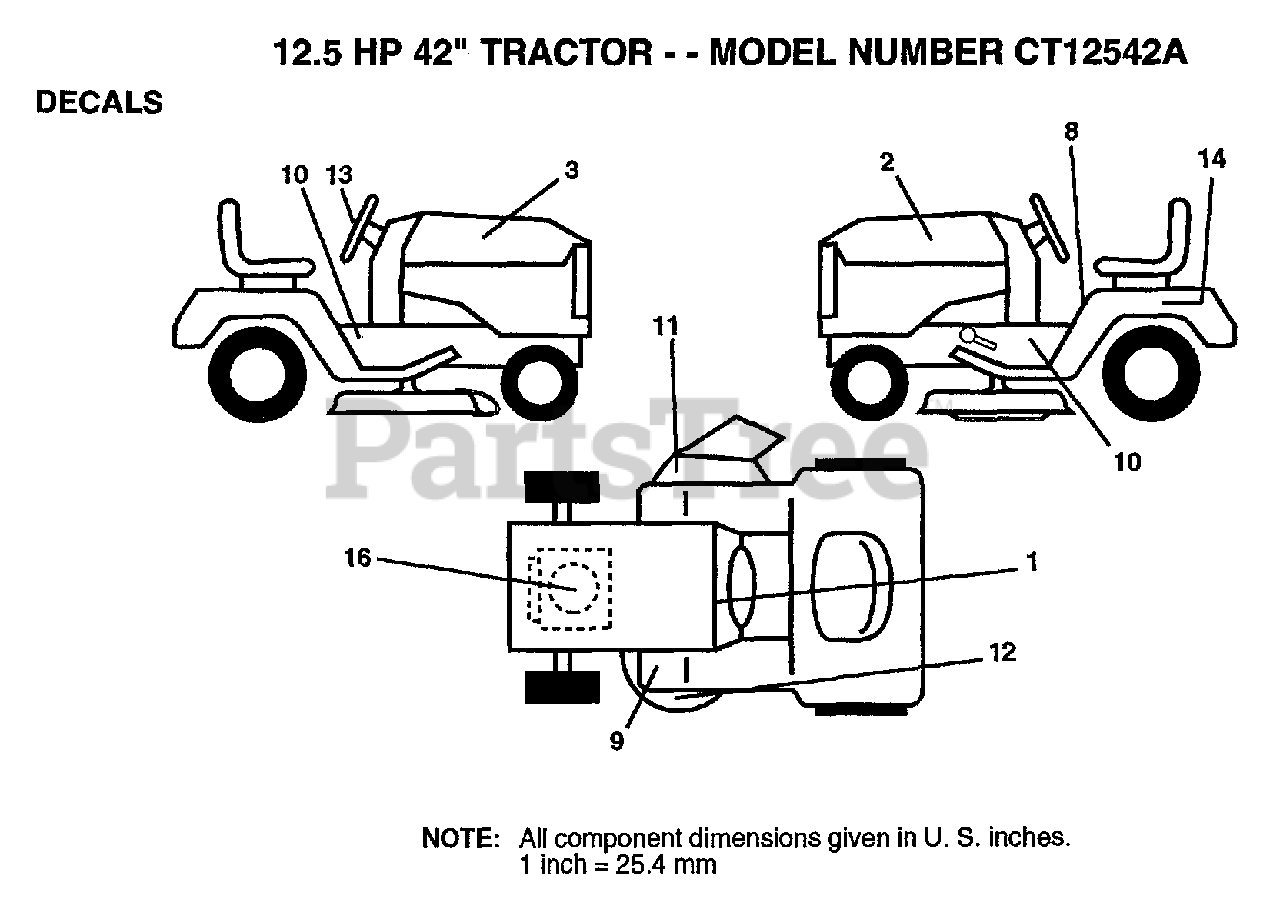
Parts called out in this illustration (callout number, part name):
2	DECAL HOOD LH
3	DECAL HOOD RH
8	DECAL
10	CHASSIS DECAL
11	DECAL WARING
12	DECAL INSTRUCTION CAUTION
14	DECAL
